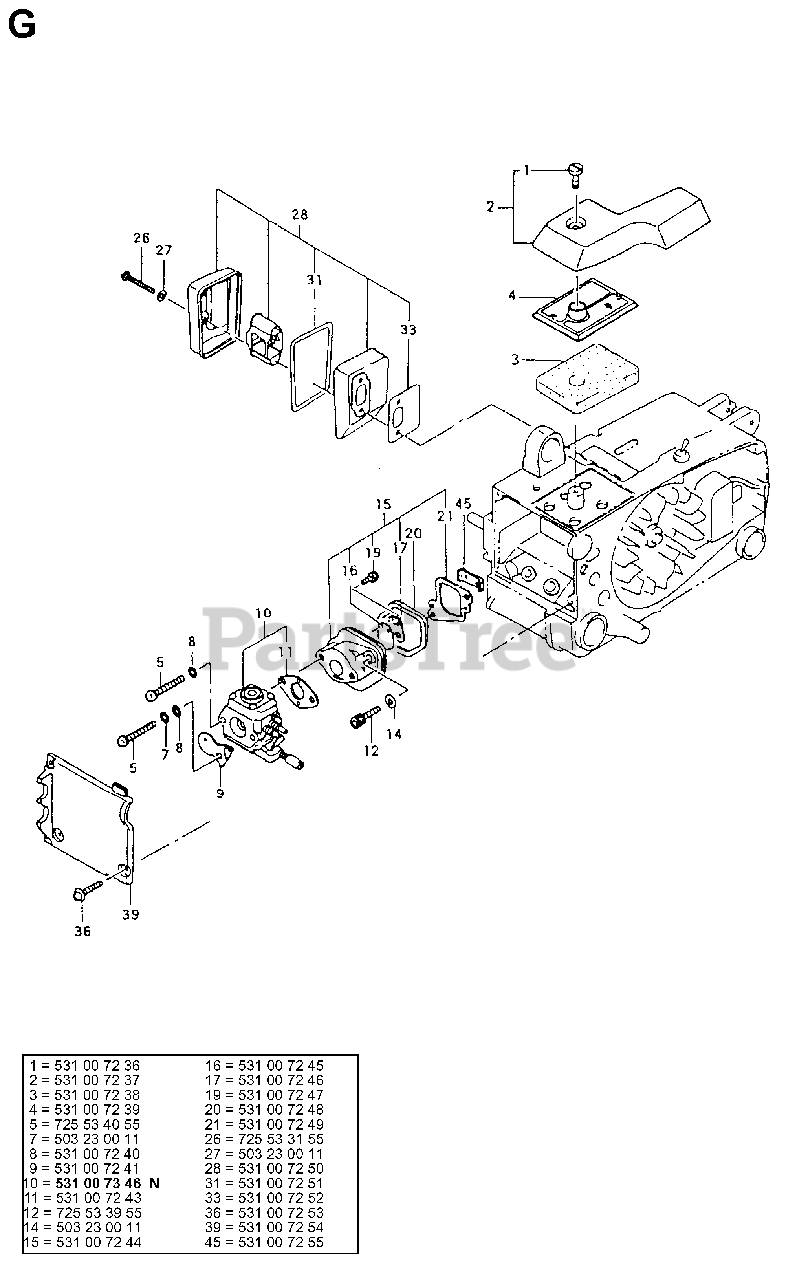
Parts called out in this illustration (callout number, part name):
5	SCREW MC6S 5X45
7	WASHER 5.3X12
9	CHOKE FLAP
10	CARBURETOR
12	SCREW MC6S 5X40
14	WASHER 5.3X12
26	SCREW MC6S 5X20
27	WASHER 5.3X12
